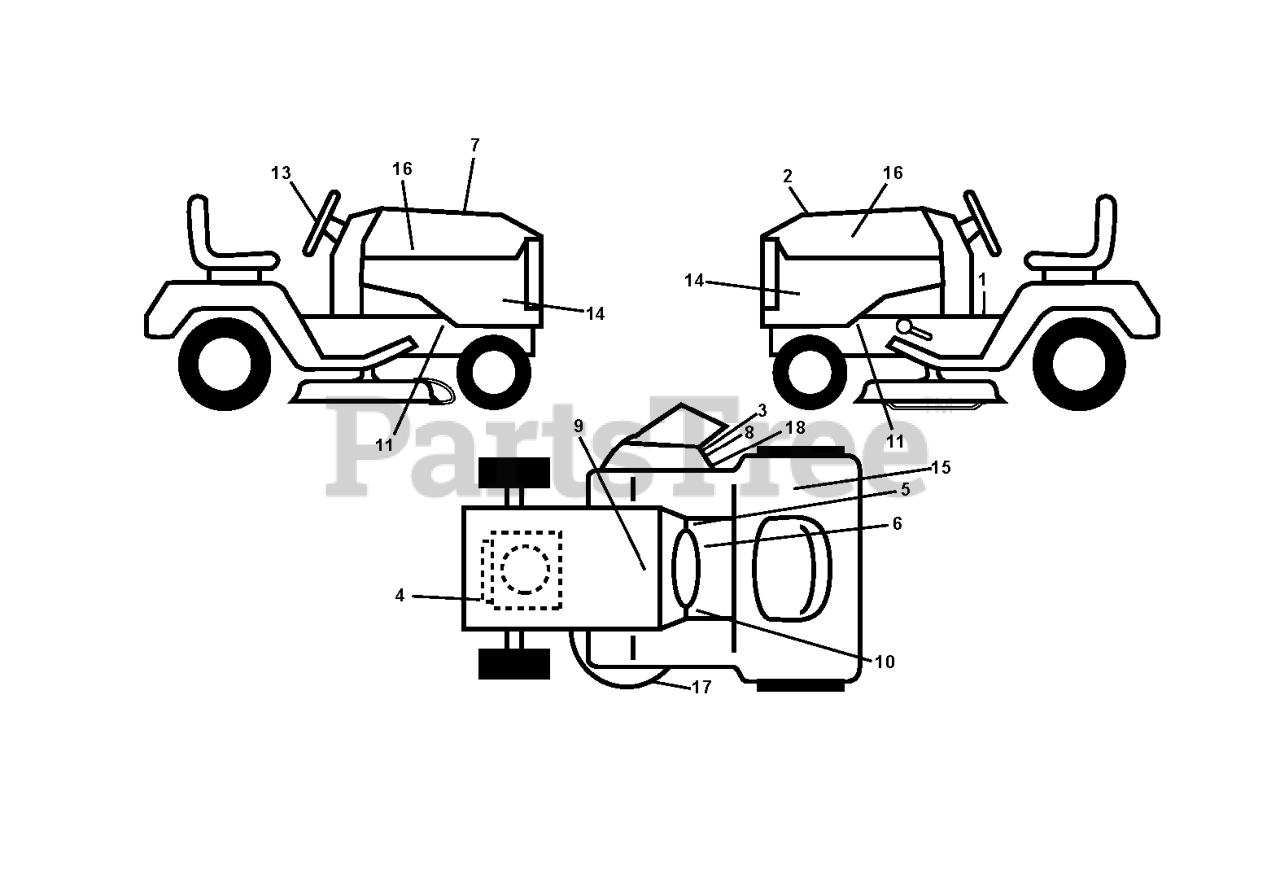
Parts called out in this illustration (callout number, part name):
1	LABEL
2	DECAL.HOOD.TOP.INSERT.
4	DECAL
5	DECAL PARK BRAKE
6	DECAL
7	DECAL RPL KO
8	DECAL.INTERNATIONL.CUTFINGER
9	DECAL BTRY SYMBOLS
10	DECAL
13	DECAL.WHEEL.STRG.LGN.H
14	DECAL PNL SD.
15	DECAL.FENDER
16	DECAL.HOOD.NAMELOGO.HUSQ
17	DECAL.MOWER.SCH.48/54
18	DECAL, DEFLECT WARNING
